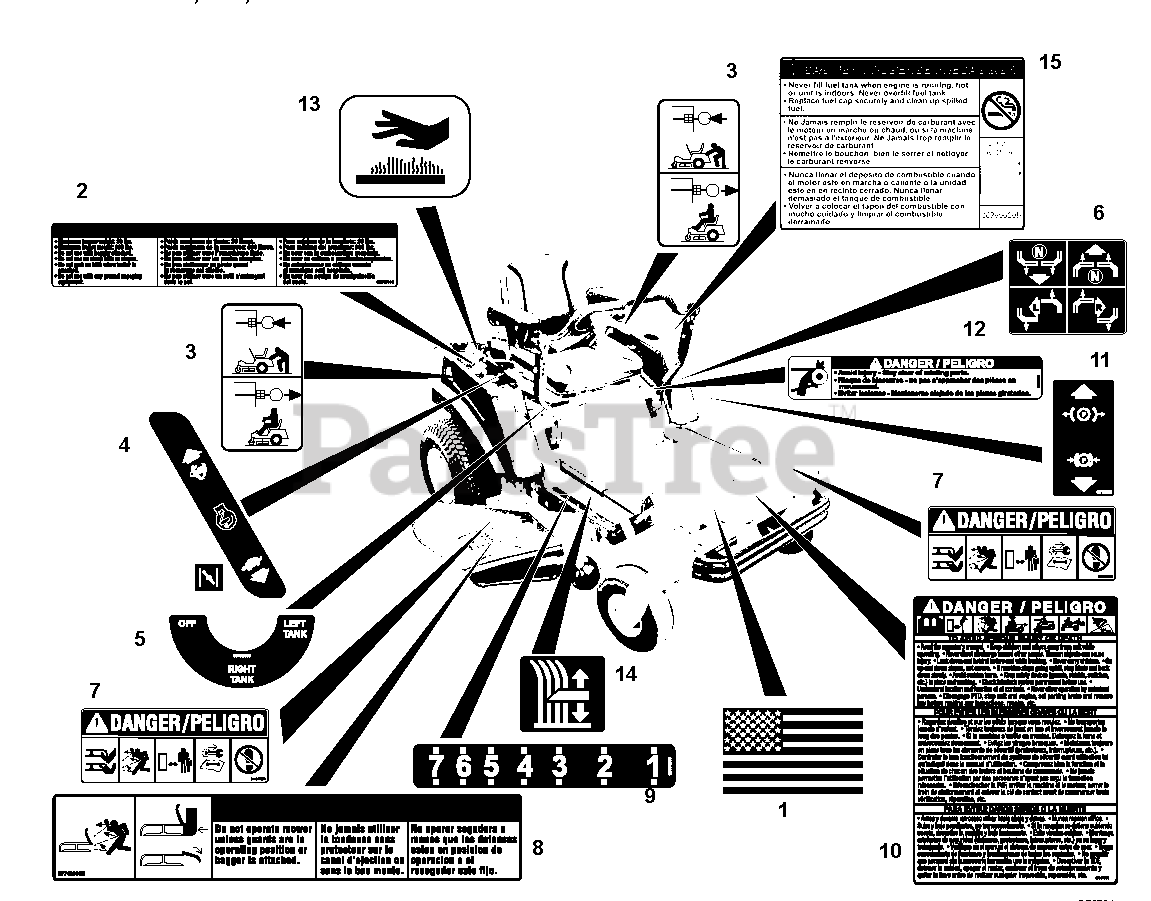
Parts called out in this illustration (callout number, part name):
1	Decal, American Flag
2	Decal, Trailer Hitch
3	Decal, Transmission Disconnect
4	Decal, Control
5	Decal, Fuel Valve
6	Decal, Instructional Steering
7	Decal, Mower Pan Head Danger
8	Decal, Warning
9	Decal, Cut Height Zoom
10	Decal, Bilingual Danger
11	Decal, Parking Brake Lever
12	Decal, Danger
13	Decal, Hot Surface
14	Decal, Cut Height
15	Decal, Fuel Warning
